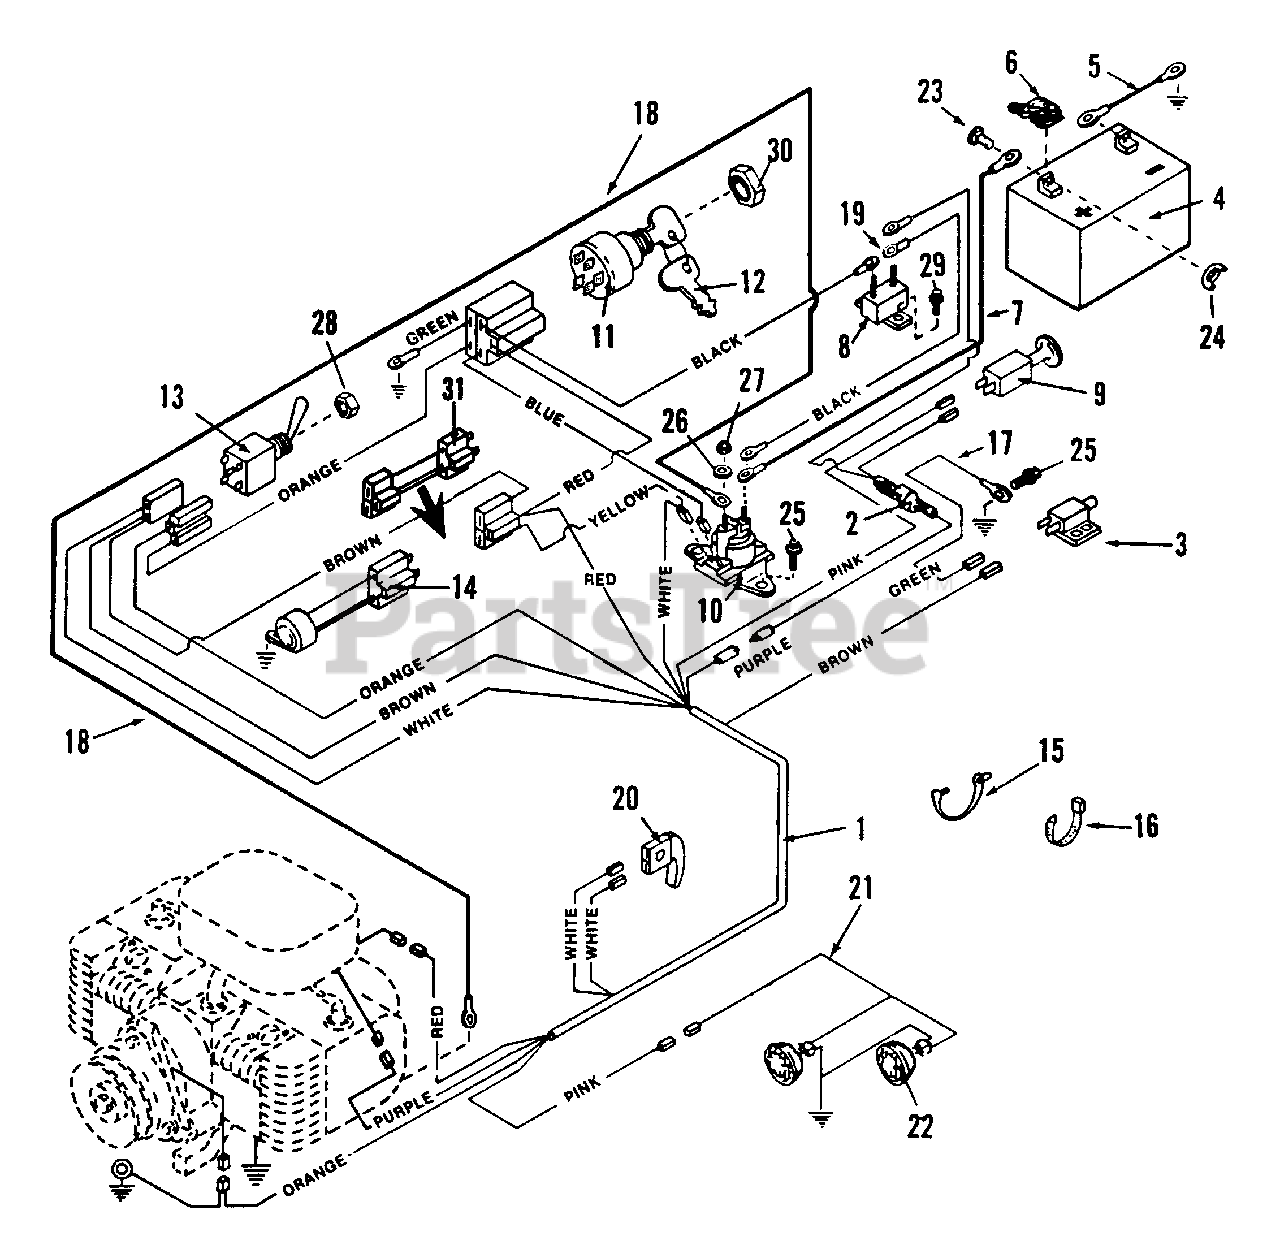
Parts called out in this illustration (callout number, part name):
1	HARNESS, Wiring
2	HARNESS, Diode
3	SWITCH, Seat Interlock (NO)
4	BATTERY 12V. 30 Amp Hour
5	CABLE, Negative (Black 15")
6	COVER, Positive Terminal
7	CABLE, Solenoid/Starter(Red 11")
8	CIRCUIT-BREAKER 20 AMP
9	SWITCH, Headlamp (NO)
10	SOLENOID
11	KEYSWITCH
12	KEY
13	SWITCH, PTO
14	MODULE, Interlock - B&S
15	TIE, Wire
16	TIE, Cable
17	WIRE, Seat Switch to Ground
18	CABLE, Solenoid/Starter (Black 36")
19	WIRE, Breaker to Solenoid
20	SWITCH, Clutch Interlock (NO)
21	HARNESS, Headlamp
22	HEAD-LAMP
23	BOLT, 1/4-20 X 3/4" Carriage
24	WING-NUT, 1/4-20
25	SCREW, 1/4-20 X 5/8" Hex Washer Self-Tap
26	WASHER, 1/4 Int. Tooth Lock
27	NUT, 1/4-20 Hex
28	NUT, Special 1/2-27 Hex
29	SCREW, #10-24 x 1/2" Hex Washer Self-Tap (Torx)
30	NUT, Special 5/8-32 Hex
31	* HARNESS, Module Repair
